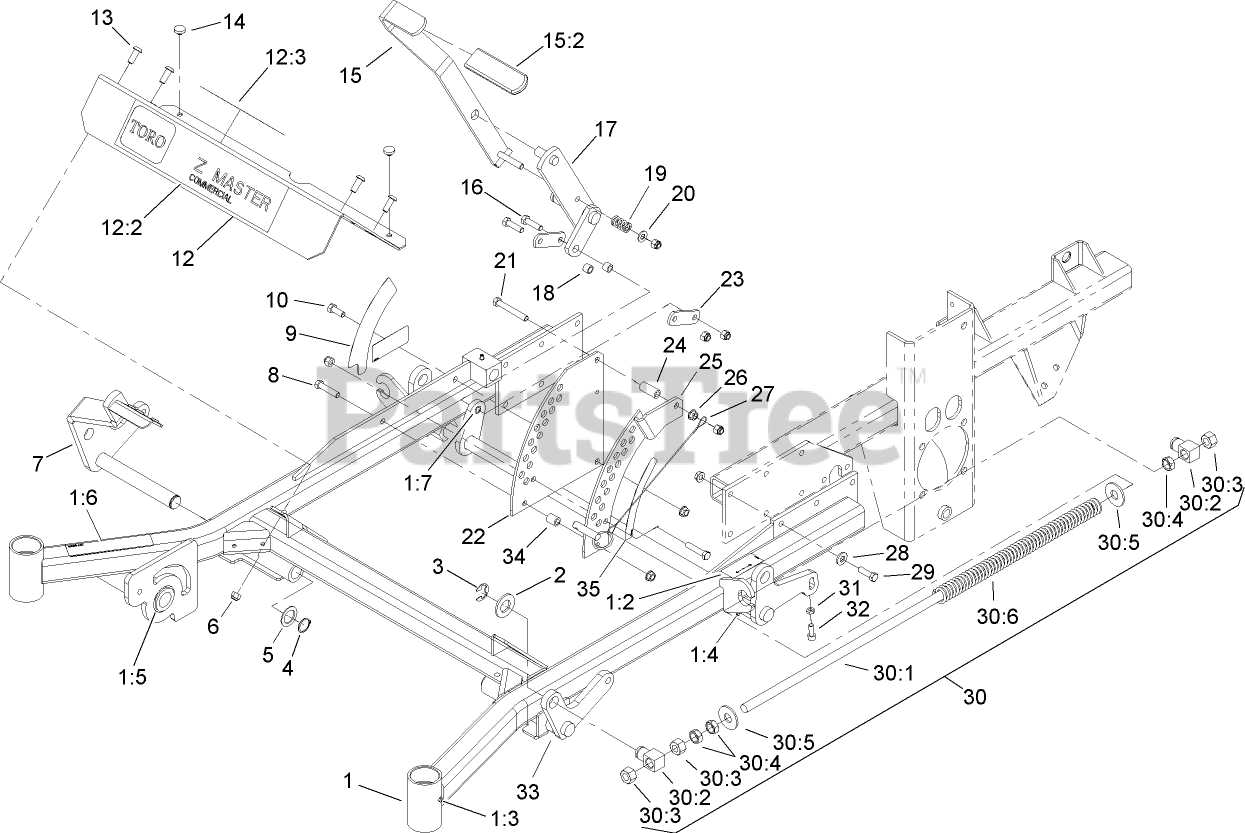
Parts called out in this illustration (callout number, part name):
1	Frame ASM
1:2	Decal-Brake, Parking
1:4	FITTING-GREASE
1:5	BUSHING
1:6	DECAL-WARNING
1:7	Bushing
2	WASHER-FLAT
3	RING-RETAINING, EXT
4	RING-RETAINING
5	WASHER-SPACER
6	NUT-LOCK, NI
7	RH Deck Lift ASM
8	SCREW-HH
9	Decal-Height, Deck
10	SCREW-HH
12	FOOTREST
12:3	DECAL-WARNING
13	SCREW-HSBH
14	BUMPER
15	LIFT LEVER/GRIP ASM
15:2	GRIP-LEVER, LIFT
16	SCREW-HH
17	ARM-LIFT, DECK
18	Bushing
19	SPRING-COMPRESSION
20	WASHER-FLAT
21	SCREW-HH
22	PLATE-LIFT, DECK
23	ARM-LIFT, DECK
24	BUSHING-LEVER, LIFT
25	PLATE-LIFT, DECK
26	NUT-HHF, WHIZ
27	Hitch Pin ASM
28	WASHER-BELLEVILLE
29	SCREW-HH
30	Front Frame Spring ASM
30:1	ROD-LIFT, DECK
30:2	SWIVEL-DECK MOUNT, REAR
30:3	NUT-HEX
30:4	NUT-JAM
30:5	WASHER-FLAT
30:6	SPRING-SUPPORT, DECK
31	NUT-JAM
32	SCREW-HSH
33	LIFT-DECK, LH
34	BUSHING-LEVER, LIFT
35	Decal-Height, Deck
